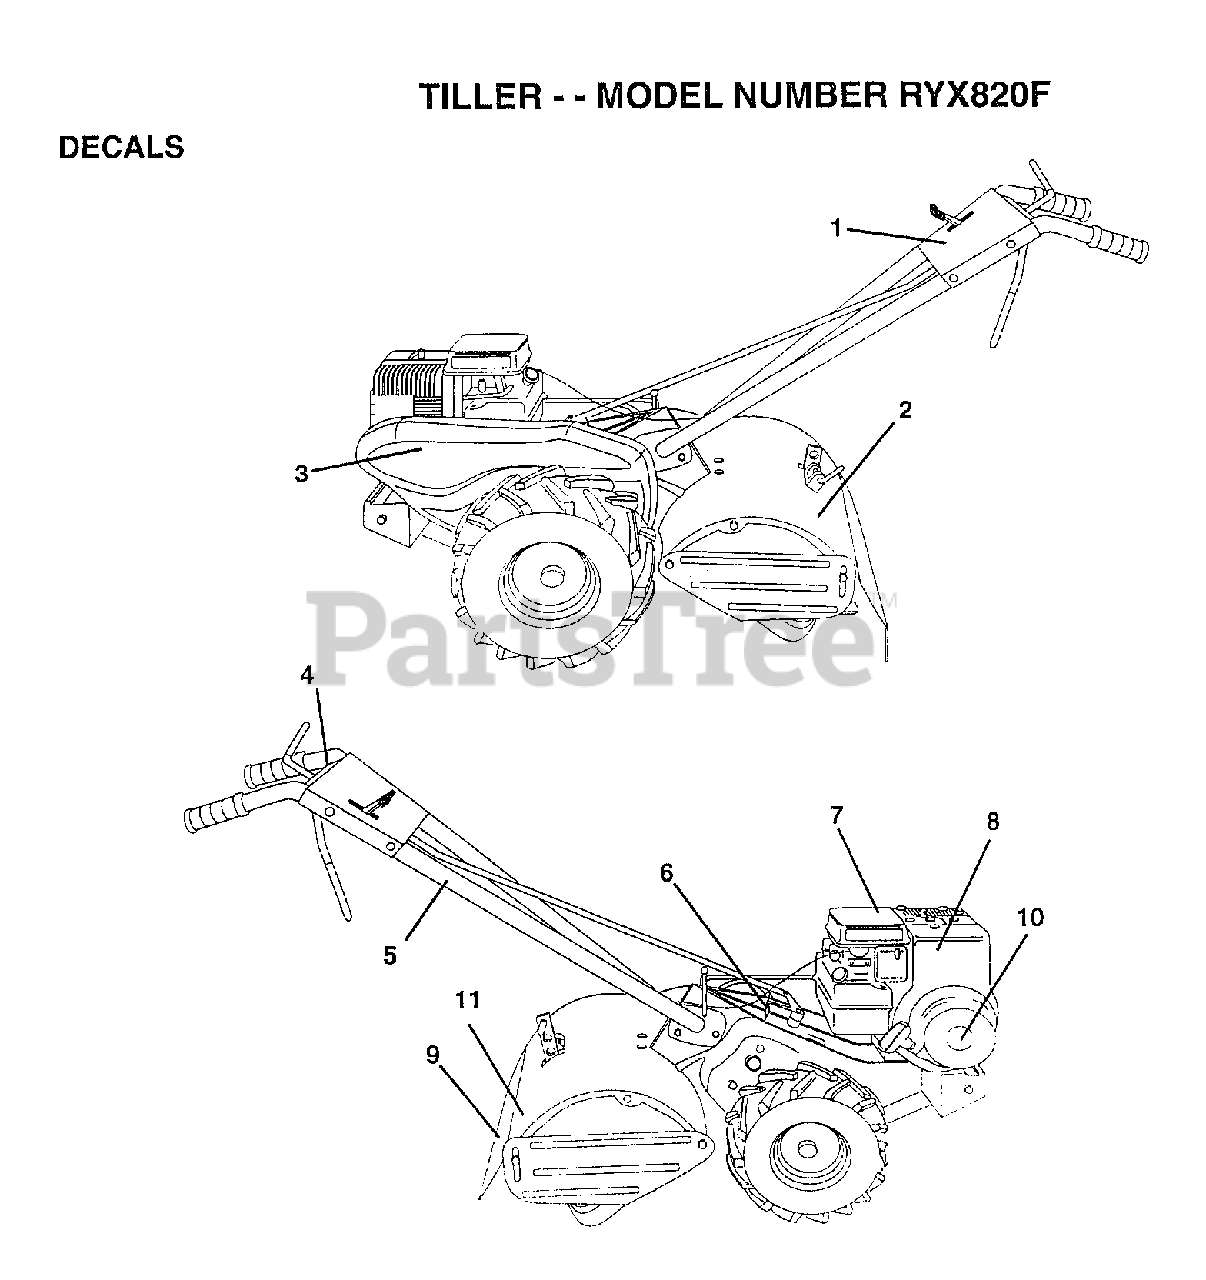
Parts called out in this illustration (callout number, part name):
3	DECAL, LOGO
5	DECAL-PLACEMENT
6	DECAL CRT
7	DECAL TI
9	DECAL-WARNING
11	DECAL.EURO.ST.CE.
